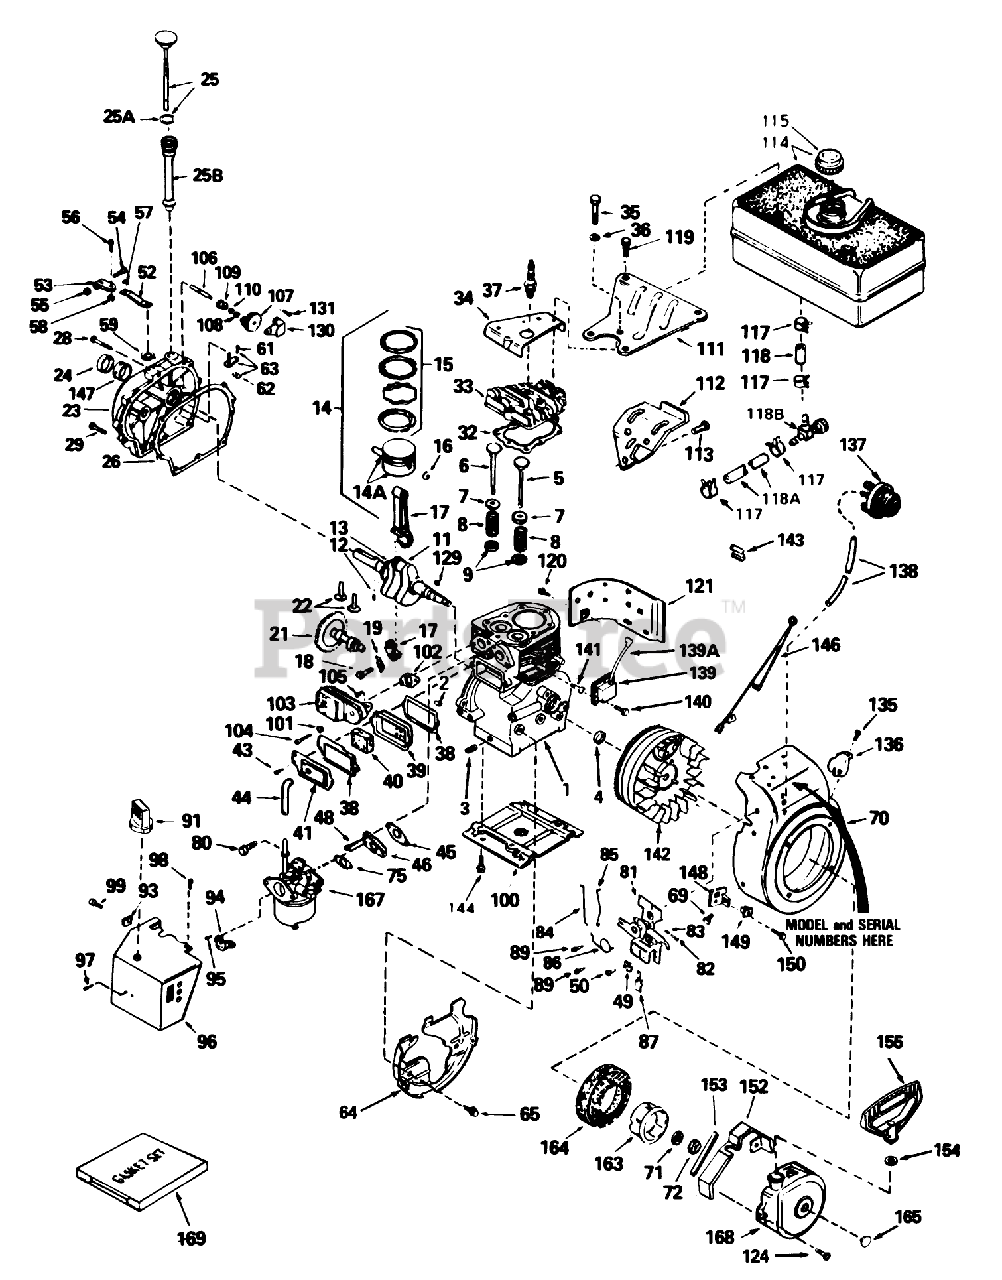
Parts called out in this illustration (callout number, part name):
1	Cylinder Assy. (Incl. Ref. #2, 3 4)
2	Pin-Dowel
3	Plug-Drain, Oil (SQH 1/4-18)
4	Oil Seal
5	Valve, Intake (Standard)(Incl. No. 9)
5	Valve, Intake (1/32" oversize)(Incl. No. 9)
6	Valve, Exhaust (Standard)(Incl. No. 9)
6	Valve, Exhaust (1/32" oversize)(Incl. No. 9)
7	Cap-Spring, Valve
8	Spring-Valve
9	Keeper-Spring, Valve
11	Crankshaft Assy. (Incl. Ref. #12 13)
12	Pin, Groove
13	Gear-Crankshaft
14	Piston, Pin Ring Assy. (Std.) (Incl. Ref. #19A, 20 21)
14	Piston, Pin Ring Assy. (.010 oversize) (Incl. Ref. #19A, 20 21 )
14	Piston, Pin Ring Assy. (.020 oversize) (Incl. Ref. #19A, 20 21)
14A	Piston Pin Assy. (Std.) (Incl. Ref. #20)
14A	Piston Pin Assy. (.010 oversize) (Incl. Ref. #20)
14A	Piston Pin Assy-. (.020 oversize) (Incl. Ref. #20)
15	ORing
15	Ring Set (.010" OS)
15	Ring Set (.020" OS)
17	Rod Assy., Connecting (Incl. Nos. 10 18)
18	Bolt-Connecting Rod
19	Dipper-Oil
21	Camshaft
22	Lifter-Valve
23	Cover, Cylinder (Incl. Nos. 24 106)
24	Oil Seal
25	Dipstick, Oil (Incl. Ref. #88)
25A	O-Ring
25B	Tube Fill
26	Gasket-Cover, Cylinder
28	Screw (1/4-20 x 1-1/4)
29	Screw
32	Gasket-Cylinder Head
33	CYLINDER HEAD
34	Cover-Head, Cylinder
35	Screw (5/16-18 X 2-1/2)
36	Washer-Flat
37	Spark Plug-Resistor (R J19 L M)
38	Gasket-Breather
39	Body-Breather
40	Element-Breather
41	Cover-Valve
43	Screw
44	Tube-Breather
45	Gasket-Intake
46	481-1279 SENATOR RO
48	Screw
49	Conduit
50	Screw (10-32 x 3/8)
52	Lever-Governor
53	Clamp-Lever, Governor
54	Screw
55	Nut-Lock
56	Screw
57	Washer-Lock
58	Nut-Lock
59	Ring-Retaining
61	Screw (6-40x5/16)
62	Yoke-Governor
63	Rod, Governor (Incl. Nos.62 63)
64	Baffle-Blower Housing
65	Screw (1/4-20x19/32)
69	Screw
70	Housing, Blower (Incl. Ref. #135 136)
71	Washer-Belleville
72	Flywheel Nut
75	Gasket-Carburetor
80	Screw-Hex Hd.
81	Control Assy., Remote Speed (Incl. Ref. #90 thru 93)
82	Screw
83	Spring-Compression
84	Governor Link
85	Link-Throttle
86	Spring-Throttle
87	Terminal
89	Screw (10-32 x 1/2)
91	Knob-Choke
93	Nut-U Type
94	Bracket-Choke
95	Screw (10-32 x 1/2)
96	Carburetor Cover
97	Screw (8-32 X 5/16)
98	Screw (10-32x1/2)
99	Screw (8-32 x 3/8)
100	Base Engine
101	Washer
102	Gasket Exhaust
103	Muffler
104	Screw (5/16-18 X 2)
105	Screw
106	Shaft-Governor
107	Governor Gear ASM
108	Ring-Retaining
109	Spool-Governor
110	Washer-Flat
111	Bracket-Fuel Tank
112	Bracket-Fuel Tank
113	Screw (1/4-20x19/32)
115	Cap, Fuel
117	Clamp-Line, Fuel
118	Line-Fuel
118A	Line-Fuel (8.62)
118B	Valve-Shut Off
119	Screw (1/4-15x7/8)
120	Screw
121	Extension-Blower Hsng.
124	Screw
129	Key-Flywheel
130	Bracket, Governor
131	Screw (10-24x1/2)
135	Screw (8-32 x 3/8)
136	Screw
137	Primer Assy.
138	Line-Primer
139	Solid State
139A	Cover-Spark Plug
140	Screw
142	Flywheel
143	Clip-Wire
144	Screw
146	Ground Wire
147	Bushing-Crankshaft
148	Bracket
149	Grommet
150	Screw
152	Guard-Starter
153	Seal, Snowguard
154	Washer
155	Handle-Starter, Mitten Grip
163	Cup-Starter
164	Screen-Starter
165	Plug-Starter
167	Carburetor (Incl. Ref. #75)
168	Starter-Rewind
169	Gasket Set
